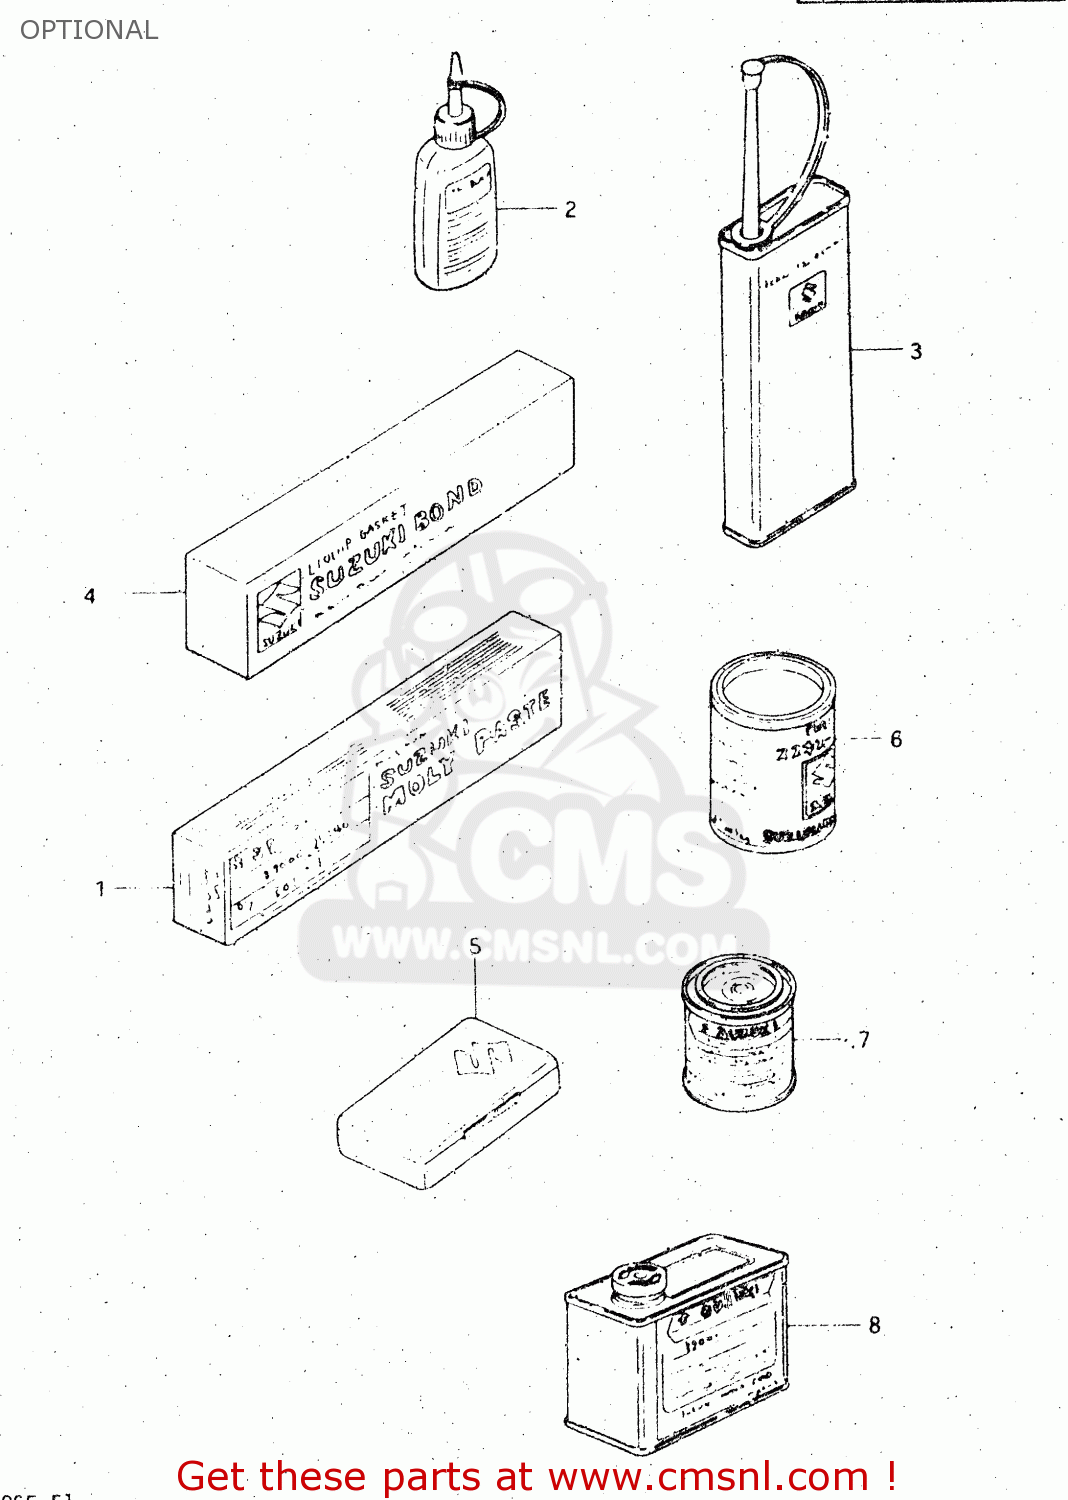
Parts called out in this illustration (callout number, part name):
1	SUZUKI MOLY PASTE
2	THREAD LOCK NO.1342
3	THREAD LOCK NO.1401 CLEAR 200G
4	LIQUID GSKT NO.1207B 100G BLK
5	TUBE REPARING TOOL
6	GREASE(C)EP2 LITHIUM 150G
7	PAINT,BLACK
8	PAINT (MARBLE CAADIAN BLUE)
